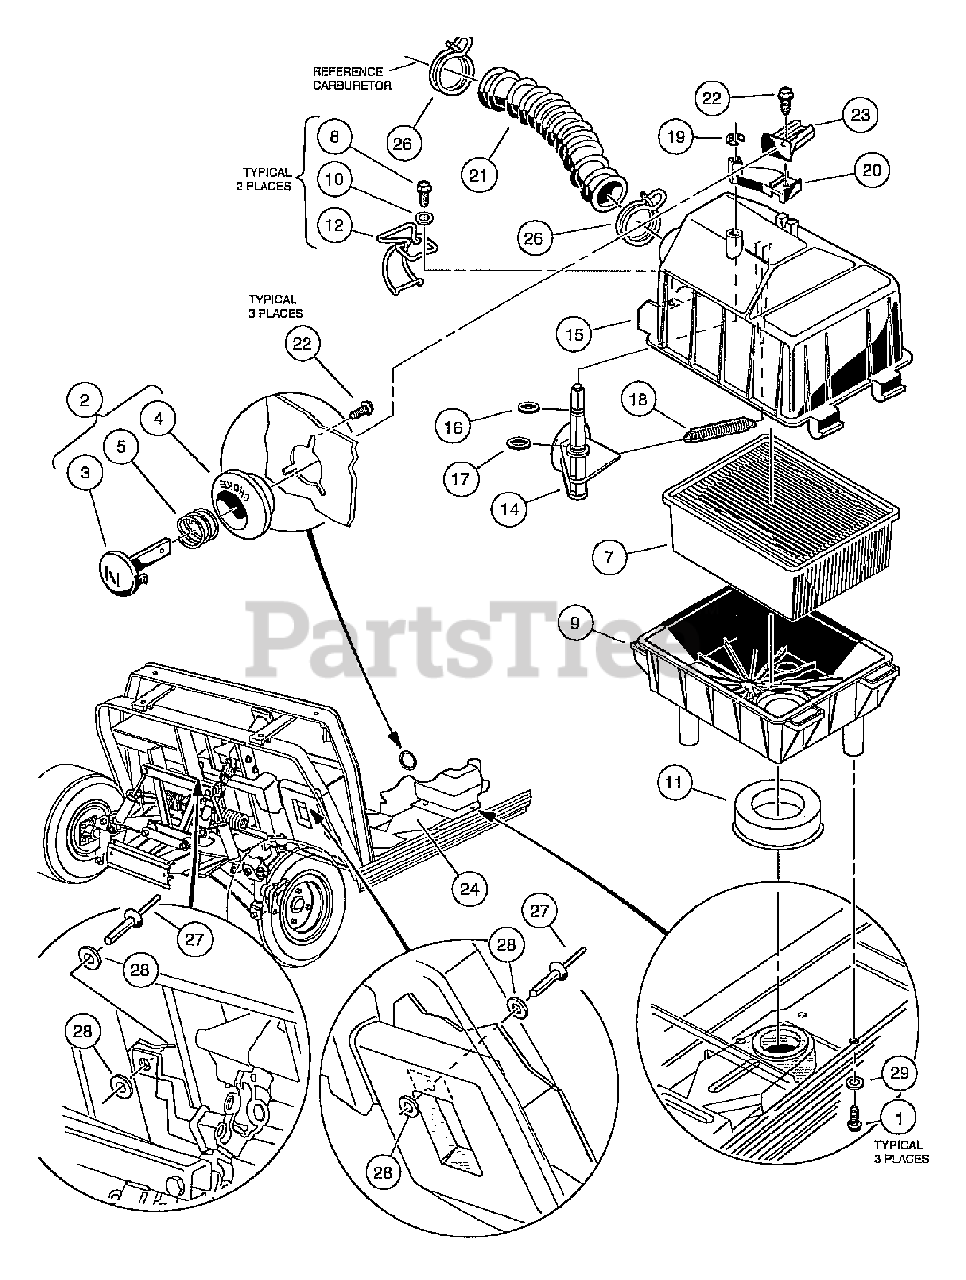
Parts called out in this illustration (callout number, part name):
1	Screw, #12-16 X 0.625 Hi-Lo
2	Button Assembly, Choke
3	Lever, Choke
4	Guide, Choke Lever
5	Compression Spring
6	Assembly, Air Box
7	Filter, Air
8	Screw, #8 X 0.500, Hex-Head Hi-Lo
9	Bottom, Air Box
10	Washer, #8 SS Flat
11	Seal, intake
12	Latch, Wireform
13	Top Assy, Air Box
14	Valve, Choke
15	Top, Air Box
16	O-Ring, 5/16
17	O-Ring, 3/8
18	Spring, Extension Return
19	Retaining Ring 0.25, Shaft
20	Lever, Choke
21	Hose, Air Intake
22	Screw, #12-16 X 0.50 Washer-Head Hi-Lo
23	Choke Positioner
24	Duct Assembly
26	Clamp, 1.58" ID Hose
27	Rivet, 3/16 X .500 Alum Pop
28	Washer, #10 Type A Flat
29	Washer, 1/4 Type A Narrow Flat
